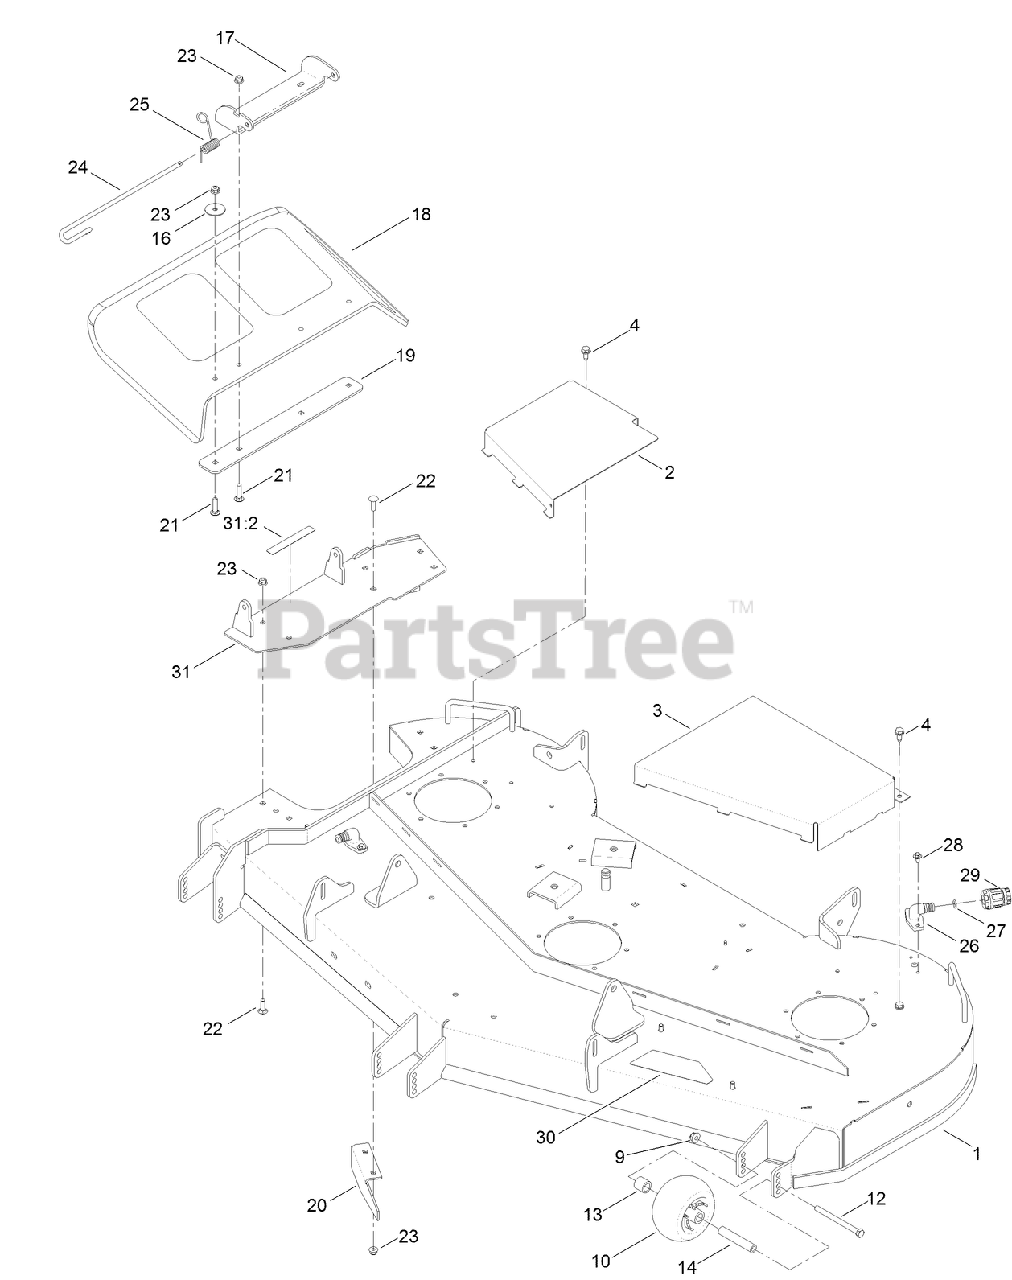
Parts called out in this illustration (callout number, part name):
1	60 INCH DECK ASM
2	COVER-BELT, RH
3	COVER-BELT, LH
4	SCREW-HWHTF
9	NUT-HF, NI
10	ROLLER-SCALP, ANTI
12	SCREW-HH
13	SPACER-AXLE, REAR
14	TUBE-SPANNER
16	WASHER-FLAT
17	BRACKET-DEFLECTOR, UPPER
18	DEFLECTOR
19	PLATE-DEFLECTOR
20	BAFFLE-CUTOFF
21	SCREW-CARR
22	SCREW-CARR
23	NUT-HF, NI
24	PIN-CHUTE
25	SPRING-TORSION
27	O-RING
28	SCREW-HHFTF
29	CONNECTOR-HOSE
31	PIVOT-DEFLECTOR
31:2	DECAL-DANGER
